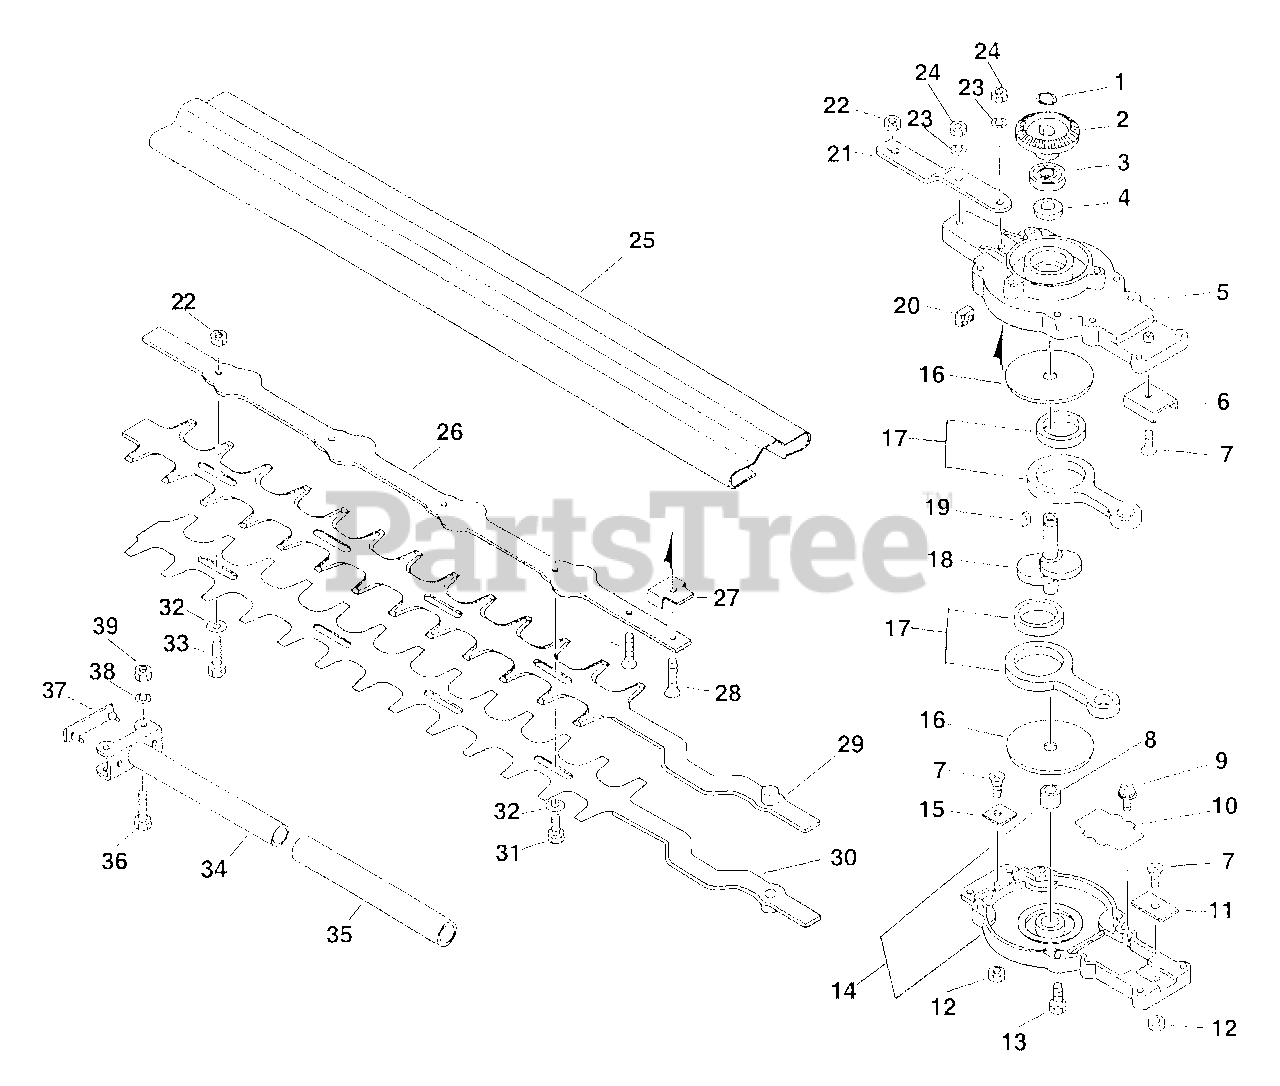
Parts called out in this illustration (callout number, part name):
1	E-RING 10
2	GEAR, SPUR
3	BEARING, BALL 6000
4	SEAL, OIL
5	CASE, GEAR
7	SCREW 4×8
8	BEARING, PLAIN
9	SCREW 3×6
10	PLATE, SIDE
11	PLATE, EYE
13	BOLT 5×20
14	GEAR CASE LID ASSY
15	PLATE, GUIDE
16	PLATE, SIDE
17	CONROD ASSY
21	SUPPORT, BLADE
23	WASHER, SPRING 5
24	NUT M5
25	SCABBARD
26	SUPPORT, BLADE
27	PLATE, ANGLE
28	SCREW 5×20
29	BLADE - UPPER -- "TB"- TOP BLADE
30	BLADE, TRIMMER - "BB"- BOTTOM BLADE
31	BOLT, CUTTER
32	WASHER 6.5×15.5×0.6
33	BOLT, CUTTER
34	ADJUSTOR ASSY, HANDLE
35	GRIP, HANDLE
36	BOLT - 5×25
37	SEAL, FELT
38	WASHER, SPRING 5
39	NUT M5
